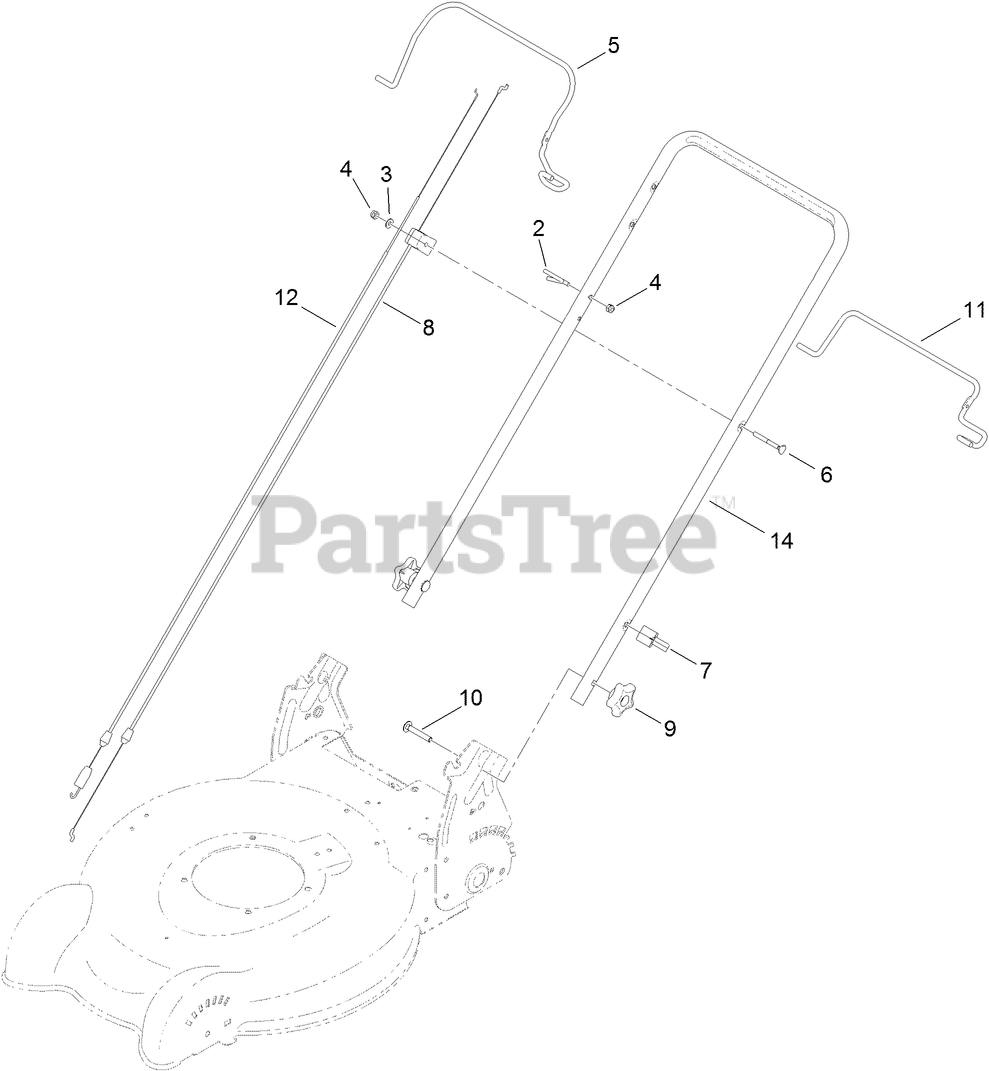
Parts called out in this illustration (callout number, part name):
2	GUIDE-ROPE
3	WASHER-FLAT
4	NUT-LOCK, NI
6	SCREW-HANDLE
7	GUIDE-CABLE
8	CABLE-BRAKE, ENGINE
9	KNOB-HANDLE
10	BOLT-CARR
11	BAIL-TRACTION, 2-BAIL FLAT
12	CABLE-TRACTION
